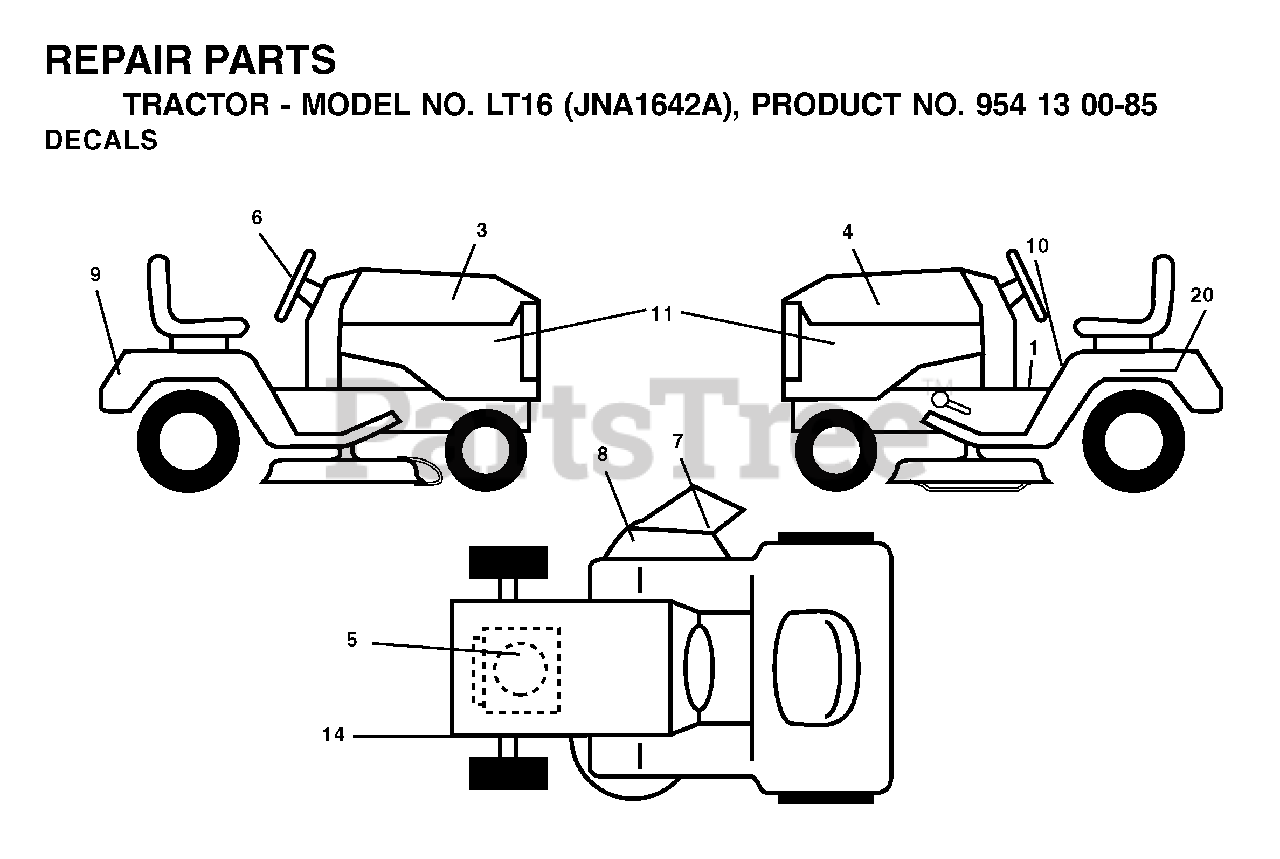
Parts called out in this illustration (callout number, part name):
1	DECAL FEND STLT OPER INST E/F
7	DECAL DECK "B" 42"
8	DECAL.WARN.KEEP.HAND.AWAY
10	DECAL FENDER DANGER
14	DECAL V BELT SCHEMATIC
20	DECAL BTRY SYMBOLS
